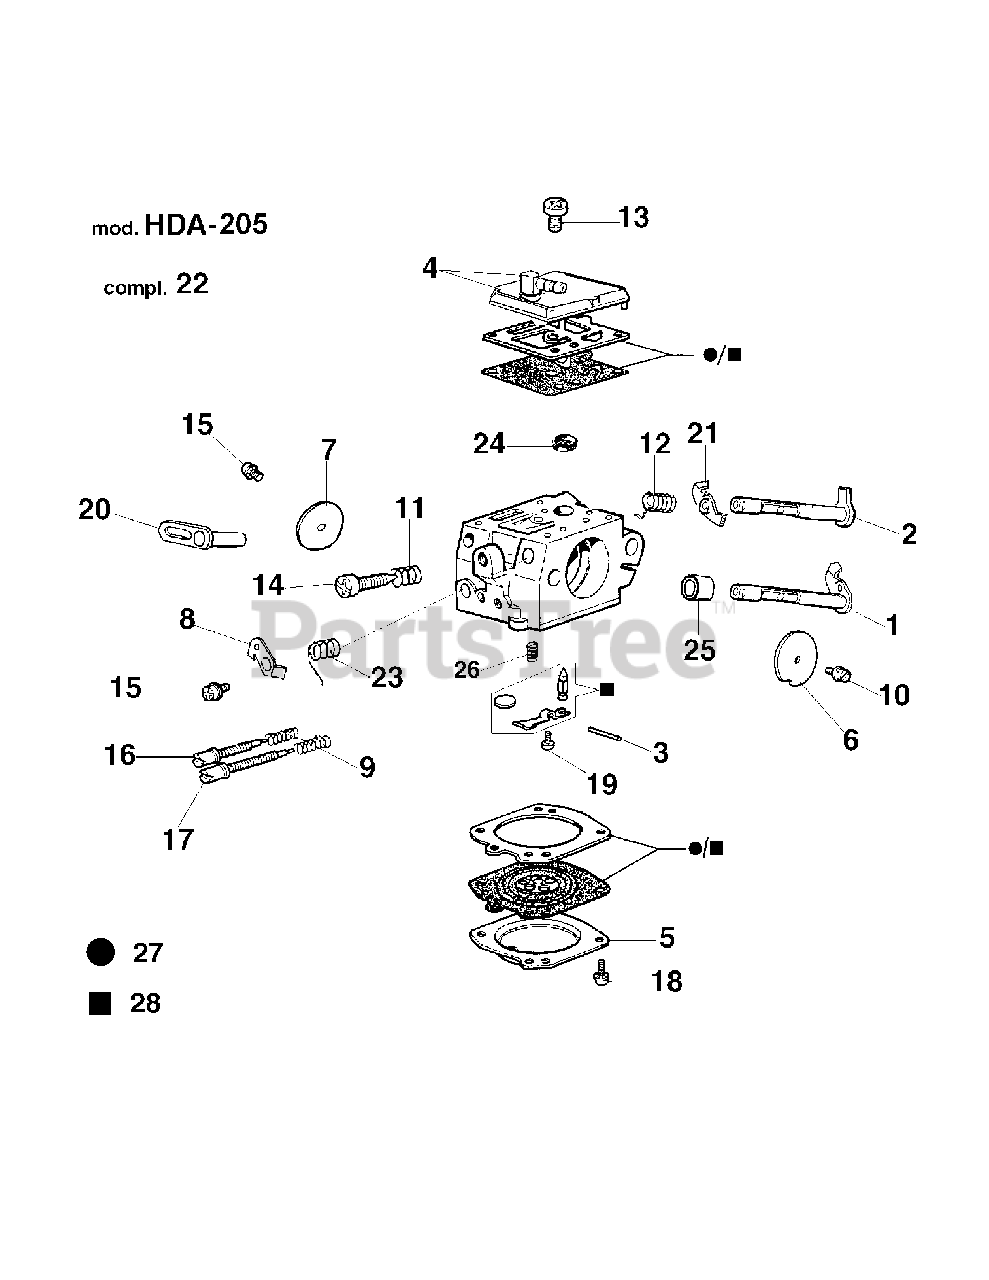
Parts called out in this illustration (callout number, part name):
1	THROTTLE SHAFT
2	STARTER SHAFT
6	THROTTLE VALVE
7	CHOKE SHUTTER
8	THROTTLE LEVER
20	STARTER LEVER
27	DIAPH./GASKETSET
